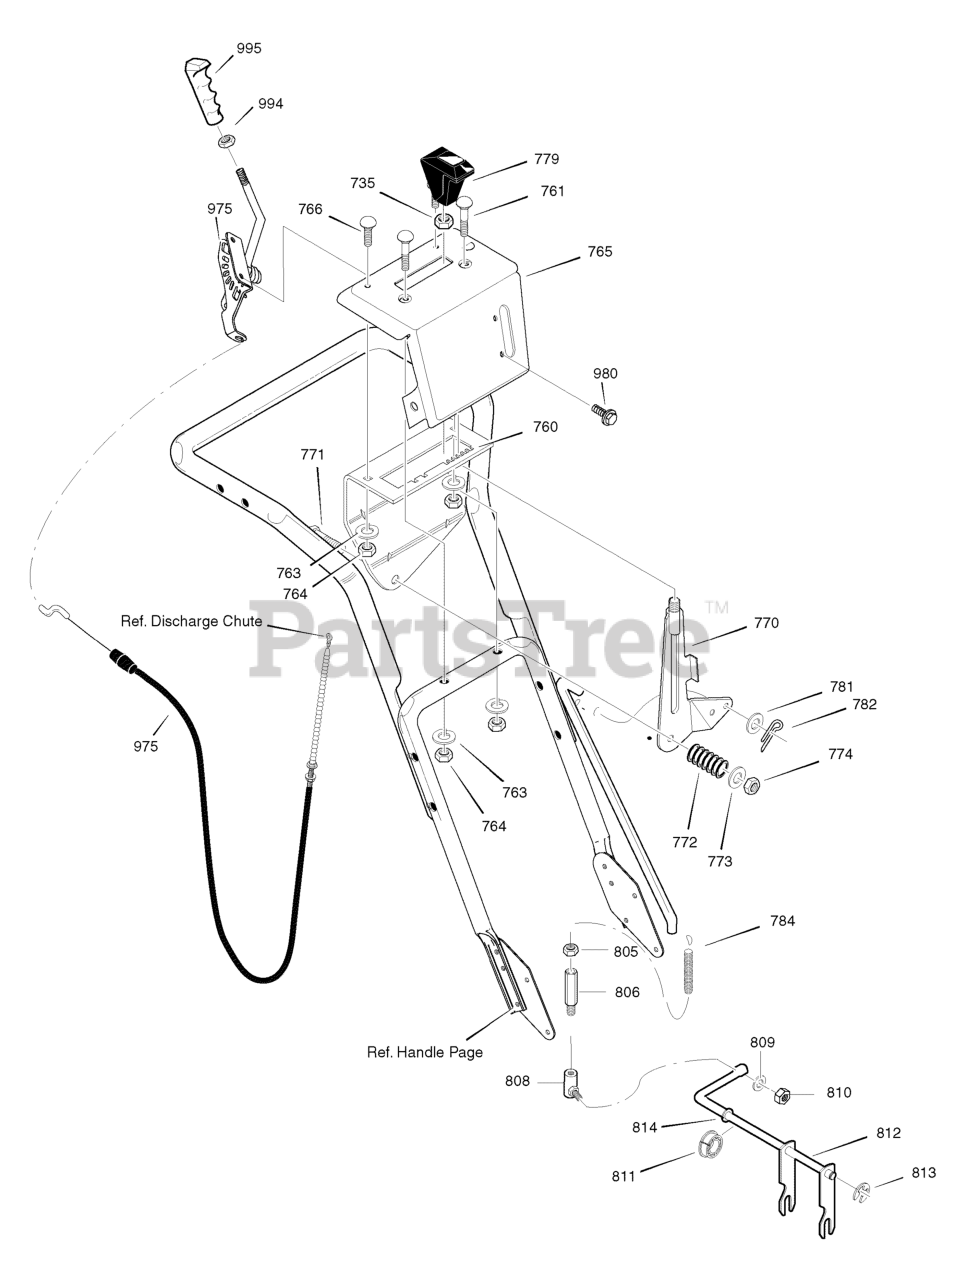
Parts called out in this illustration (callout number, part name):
735	NUT, 3/8-16 HEXJAM
760	BRACKET, SHIFT CONTROL
761	CARRIAGE BOLT, 1/4-20 x 2.00
763	WASHER, SPLIT
764	NUT, 1/4-20 HEX
765	CONTROL PANEL
766	CARRIAGE BOLT, 1/4-20 X .63
770	SHIFT LEVER ASSEMBLY
771	SCREW, 5/16-18 X 1.75
773	FLATWASHER
774	NUT, 5/16-18 NYLON HEX
781	WASHER, FLAT .349 X .69 X .066
782	PIN, COTTER
784	ROD, SPEED CONTROL
805	NUT, 5/16-24
806	ADAPTER, SPEED ROD ASSEMBLY
808	BALLJOINT, STEEL -YZ
809	WASHER
810	NUT, 5/16-24
811	FLANGED BEARING
812	ROD ASSEMBLY, YOKE PANEL
813	RING, RETAINER
975	LEVER & CABLE, CHUTE DEFLECTOR
980	SCREW
994	NUT, 3/8-16
995	KNOB, SHIFT
